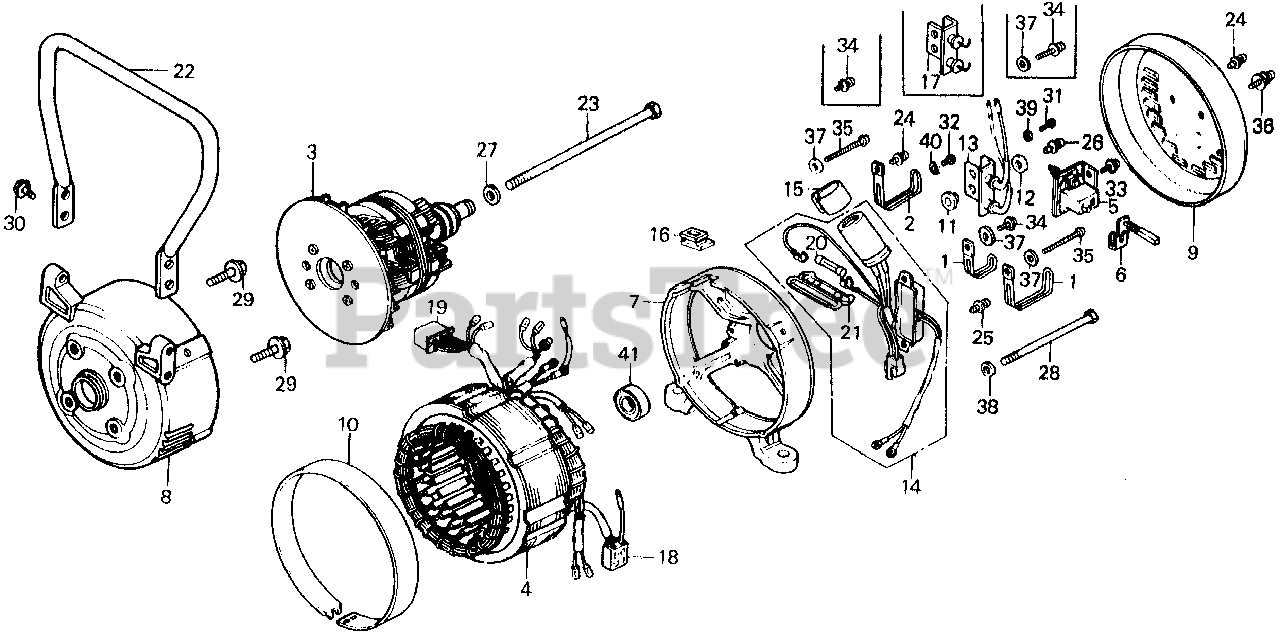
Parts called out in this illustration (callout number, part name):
1	CLAMP A, WIRE
2	CLAMP B, WIRE
3	ROTOR
4	STATOR ASSY.
5	HOLDER, BRUSH
7	HOUSING, RR. *R8* (BRIGHT RED)
7	HOUSING, RR. *R8* (BRIGHT RED) (NOT AVAILABLE)
8	HOUSING, FR. *R8* (BRIGHT RED)
9	COVER, GENERATOR END *R8* (BRIGHT RED)
10	COVER, STATOR *R8* (BRIGHT RED)
11	BUSH, INSULATING
12	WASHER, INSULATING
13	DIODE ASSY.
14	REGULATOR ASSY., AUTOMATIC VOLTAGE
14	REGULATOR ASSY., AUTOMATIC VOLTAGE (NOT AVAILABLE)
15	HOLDER B
17	DIODE, D.C. (NOT AVAILABLE)
18	CONNECTOR, FEMALE (4 POLE)
19	CONNECTOR, FEMALE (6 POLE)
20	FUSE (2.5A)
21	HOLDER, FUSE
22	HANDLE, CARRY (NOT AVAILABLE)
23	BOLT, HEX. (5/16X136)
24	SCREW, TAPPING (5X12)
25	SCREW, TAPPING (5X14)
26	SCREW, TAPPING (5X16)
27	WASHER (8MM)
28	BOLT, HEX. (6X115)
28	BOLT, HEX. (6X115) (NOT AVAILABLE)
29	BOLT-WASHER (8X25)
29	BOLT-WASHER (8X35) (NOT AVAILABLE)
30	BOLT-WASHER (8X25) (NOT AVAILABLE)
31	SCREW, PAN (4X8)
32	SCREW, PAN (5X10) (NOT AVAILABLE)
33	SCREW-WASHER (5X10)
34	SCREW-WASHER (5X16)
35	SCREW, PAN (5X60) (NOT AVAILABLE)
36	SCREW-WASHER (5X10)
37	WASHER, PLAIN (5MM)
38	WASHER, PLAIN (6MM)
39	WASHER, SPRING (4MM)
40	WASHER, SPRING (5MM)
41	BEARING, RADIAL BALL (6203UU)
